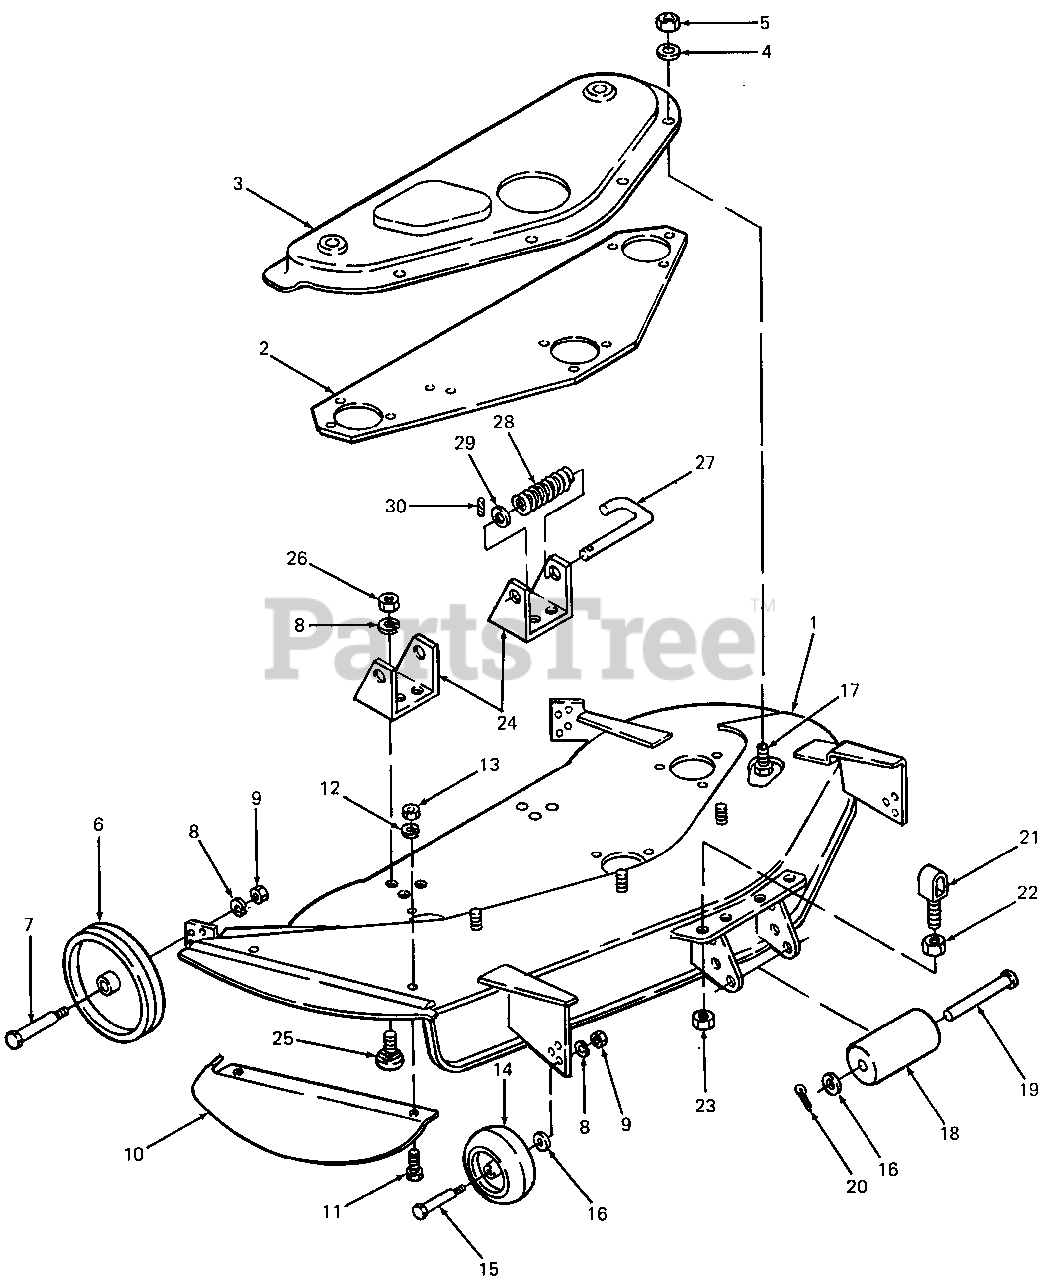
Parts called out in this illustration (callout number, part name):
2	Plate, Spindle Mtg.
5	Nut, Hex, 5/16-18 GR5
6	Wheel, Plastic, 6"
7	Screw, Shoulder
8	Washer, Lock, 3/8
9	Nut, Hex, 3/8-16 GR5
12	Washer, Lock, 5/16
13	Nut, Hex, 5/16-18 GR5
14	Wheel, 5" Deck
15	Bolt, Shoulder
16	Washer, Flat, .510 X 1.0 X .06
17	Screw, Hex Cutting, 5/16-18 X .62 Lg
18	Roller, Front
19	Pin, Clevis, 1/2 Dia X 7.0 Lg
20	Pin, Cotter, 3/16 Dia X 1.0 Lg
21	Hanger, Front Mower Support
22	Nut, Hex Jam, 5/8-11 GR5
23	Nut, Hex Insert Top Lock, 5/8-11 GR5 5/8-11 GR5
26	Nut, Hex, 3/8-16 GR5
27	Pin, Mower Support
28	Spring, Compression
29	Washer, Flat, .531 X .930 X .050
30	Pin, Spirol Spring, 3/16 Dia X .75 Lg
